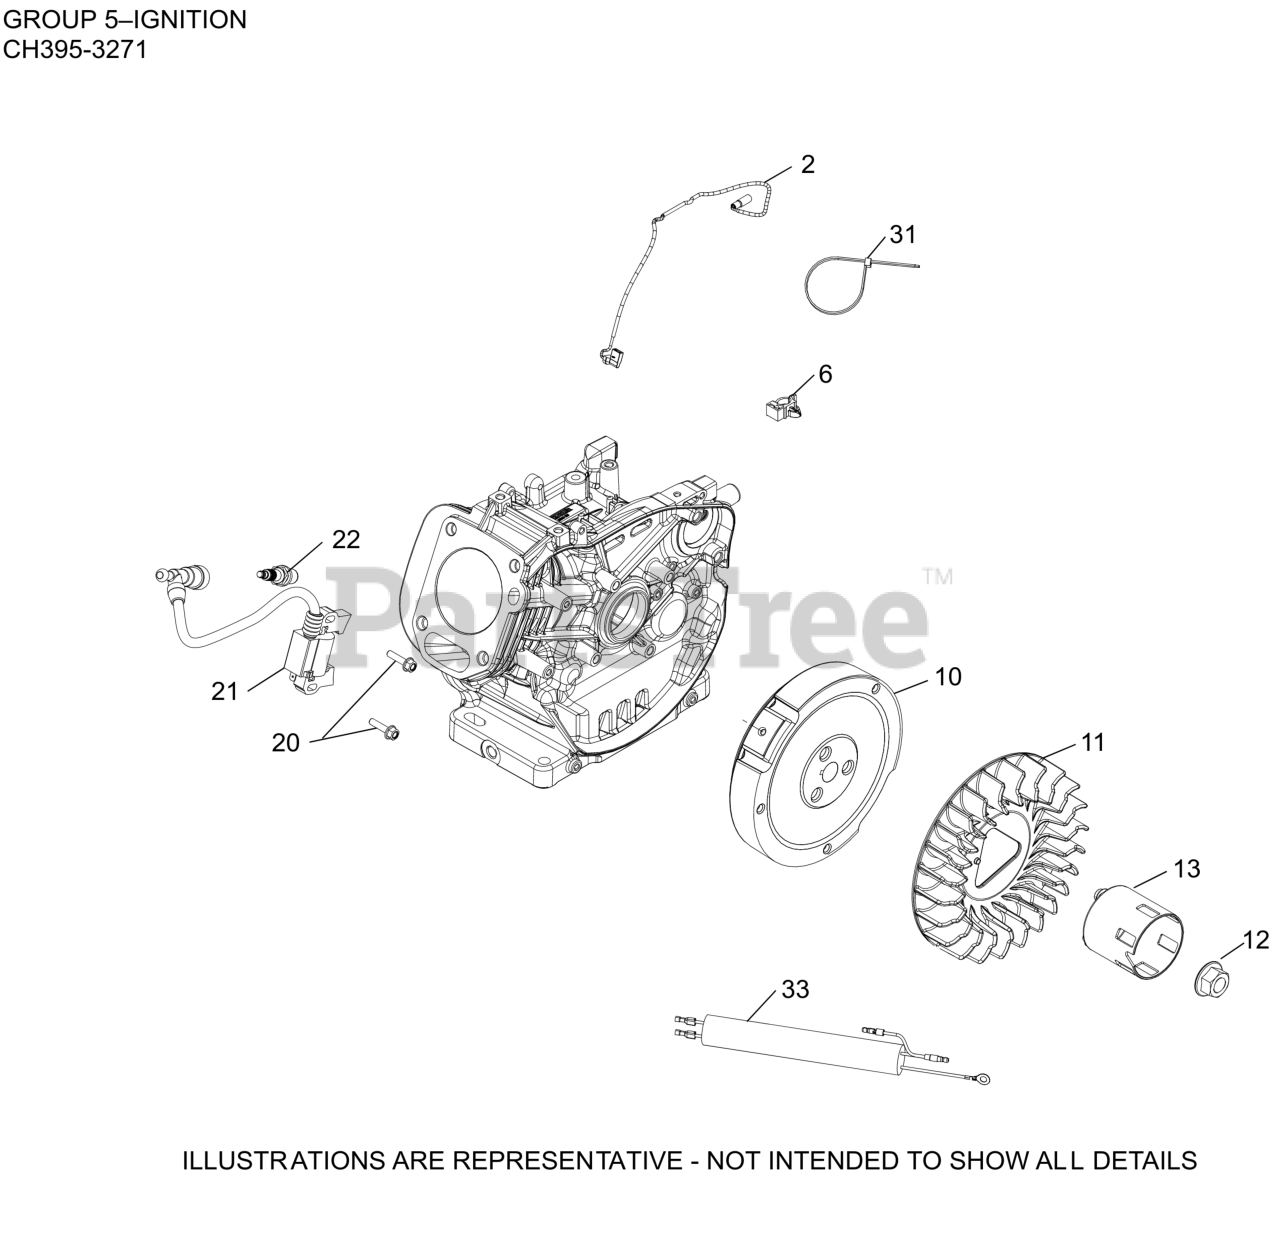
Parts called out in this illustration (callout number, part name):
2	LEAD, GROUND TO KILL
6	CLIP, WIRE HARNESS
10	FLYWHEEL ASSY,CAST IRON (RECOIL)
11	FAN, FLYWHEEL
12	NUT, FLYWHEEL
13	CUP, STARTER DRIVE
20	SCREW, M6 X 25-(#25086436S)
21	MODULE, SPARK PLUG ASSY
22	SPARK PLUG
33	LEAD, MICROSWITCH
